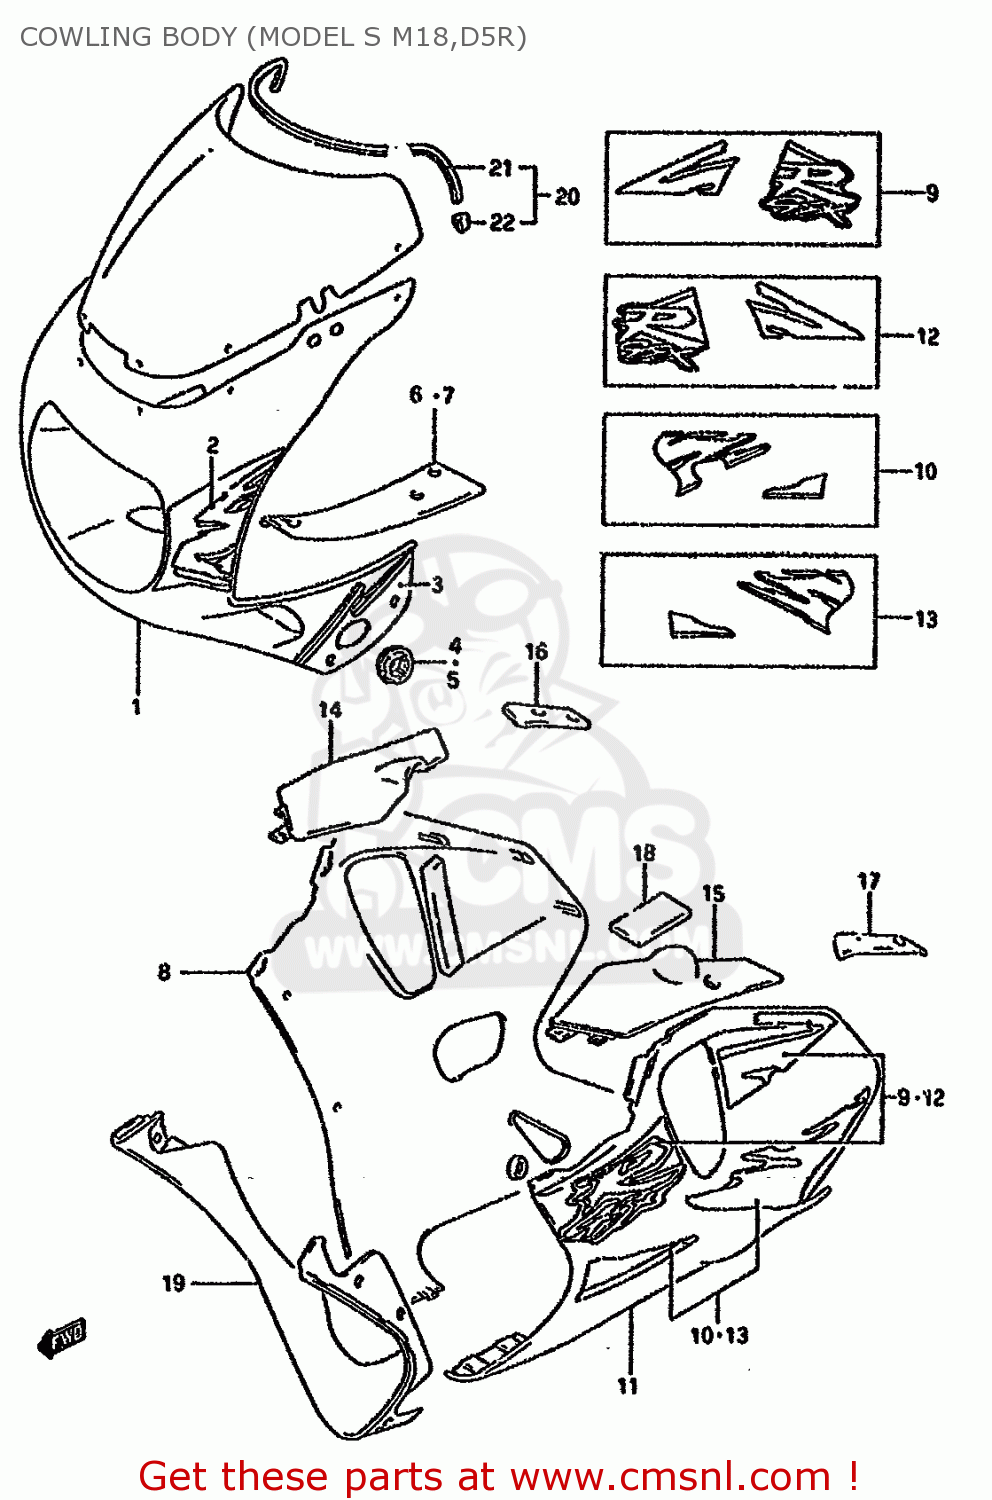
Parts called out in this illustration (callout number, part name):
1	COWLING ASSEMBLY,BODY
2	TAPE SET,COWL BODY FR
3	TAPE SET,COWLING BODY
4	PLATE,TURN SIGNAL,RIGHT
5	PLATE,TURN SIGNAL,LEFT
6	PANEL,COWLING,UPPER,RIGHT
7	PANEL,UPPER,LEFT
8	COWLING,UNDER,
9	TAPE SET,UNDER RH
10	TAPE SET,UNDER LOWER RH
11	COWLING,UNDER,
12	TAPE SET,COWL UNDER,L
13	TAPE SET,UNDER LOWER LH
14	PANEL,LWR FR,R
15	PANEL,LWR FR,L
16	PANEL,LWR RR,R
17	PANEL,LWR RR,L
18	CUSHION,PANEL
19	COWLING,UNDER CTR
20	SCREEN SET,WINDOW
21	MOLDING WINDSCREEN
22	CLIP,WINDSCREEN MOLDING
